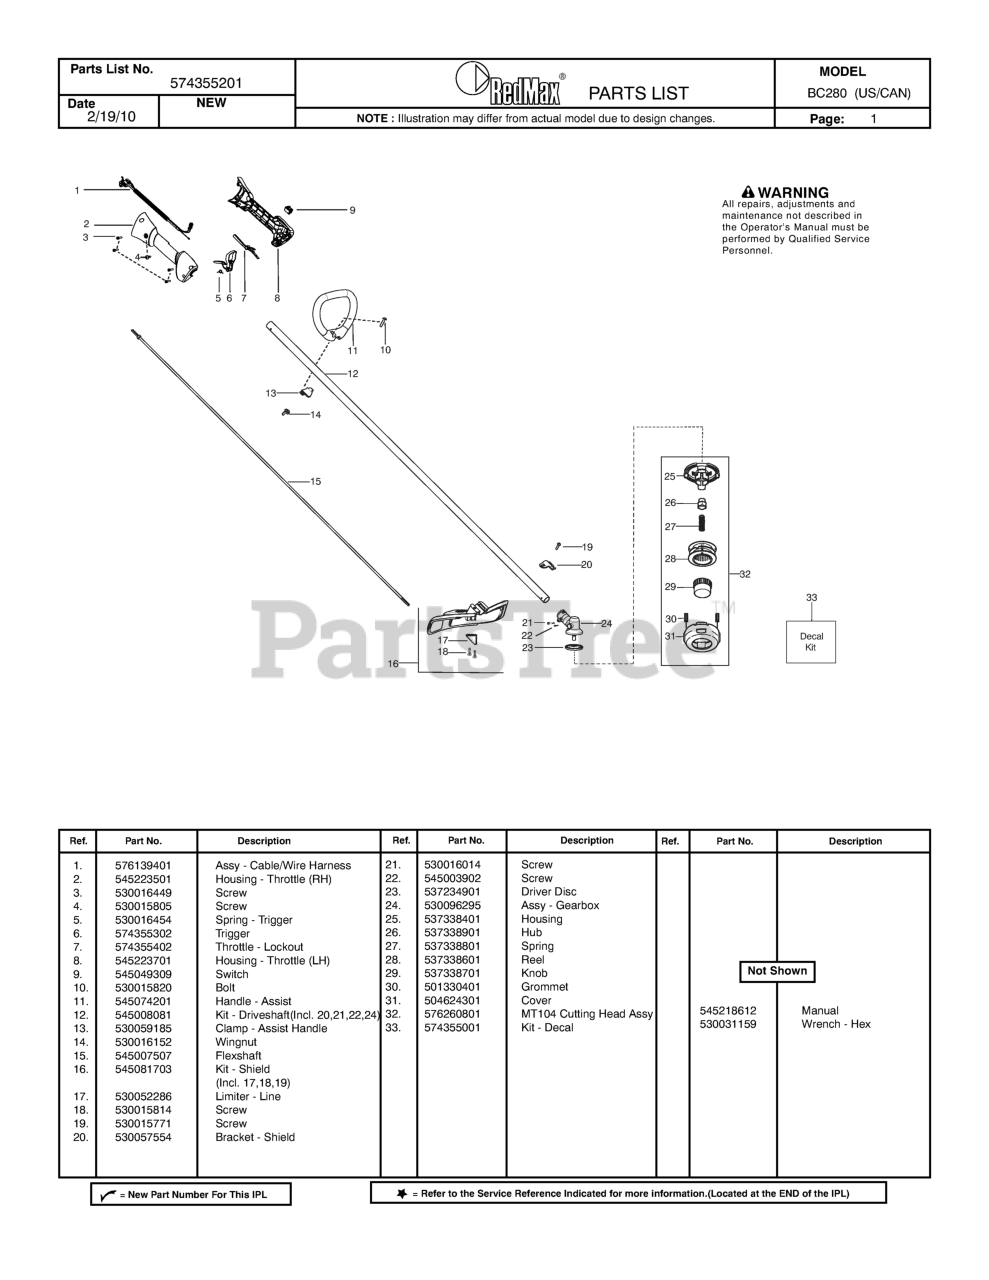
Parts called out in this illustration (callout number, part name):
1	ASSY CABLE/WIRE HARNESS
2	HOUSING-THROTTLE (RH)
4	SCREW
5	SPRING-TRIGGER
7	THROTTLE-LOCKOUT
8	HOUSING-THROTTLE LH
11	HANDLE ASSIST
12	KIT-DRIVESHAFT
13	CLAMP HANDLE
14	WINGNUT
15	FLEXSHAFT
16	KIT-SHIELD
17	LIMITER-LINE
20	BRACKET-SHIELD
23	DRIVE DISC
24	GEAR\BOX ASSY
32	MT104 CUTTING HEAD ASSY
33	KIT-DECAL
NI	WRENCH-HEX
